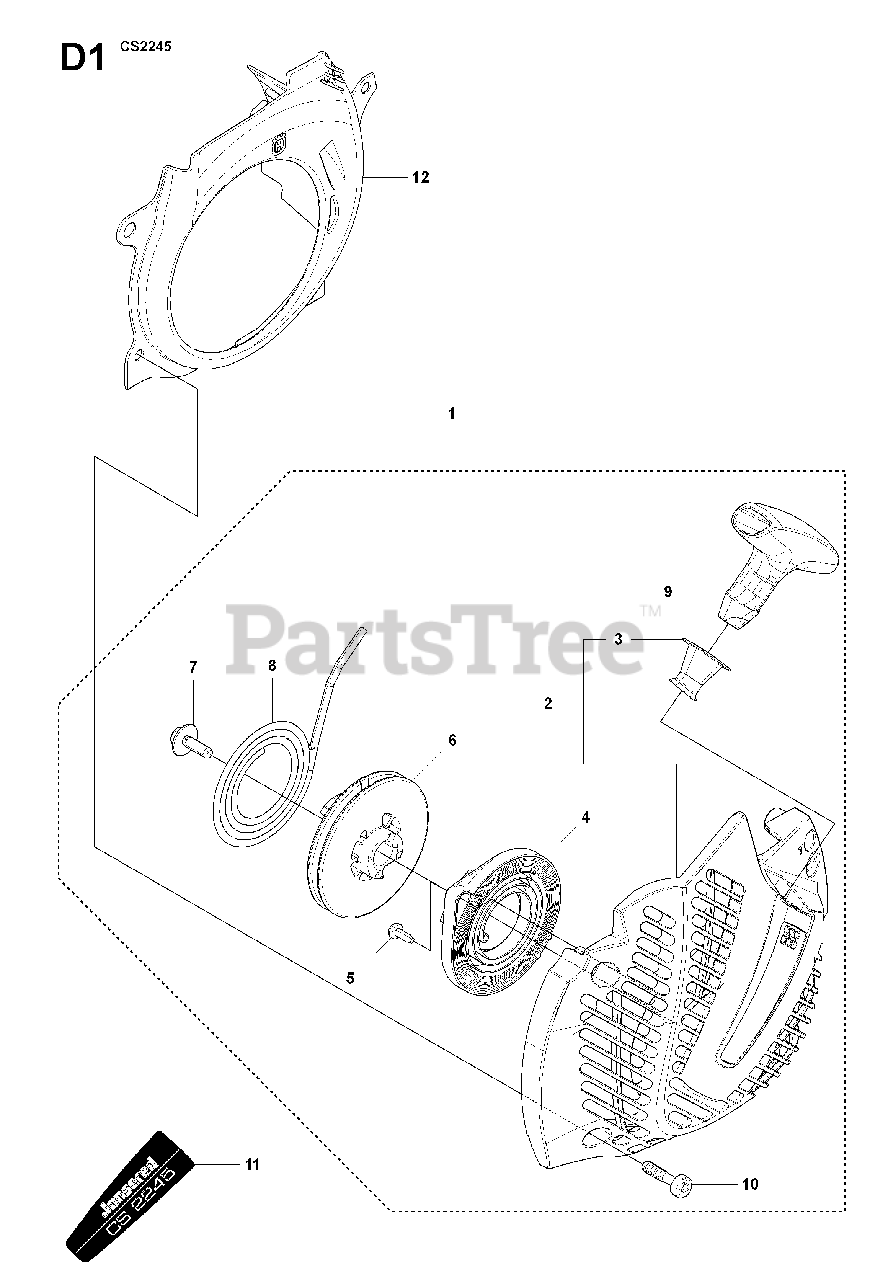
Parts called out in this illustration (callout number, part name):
1	STARTER ASSY
2	STARTER HOUSING
4	RETURN SPRING
6	PULLEY
8	STARTER ROPE
9	STARTER HANDLE
12	COOLING AIR CONDUCTOR
